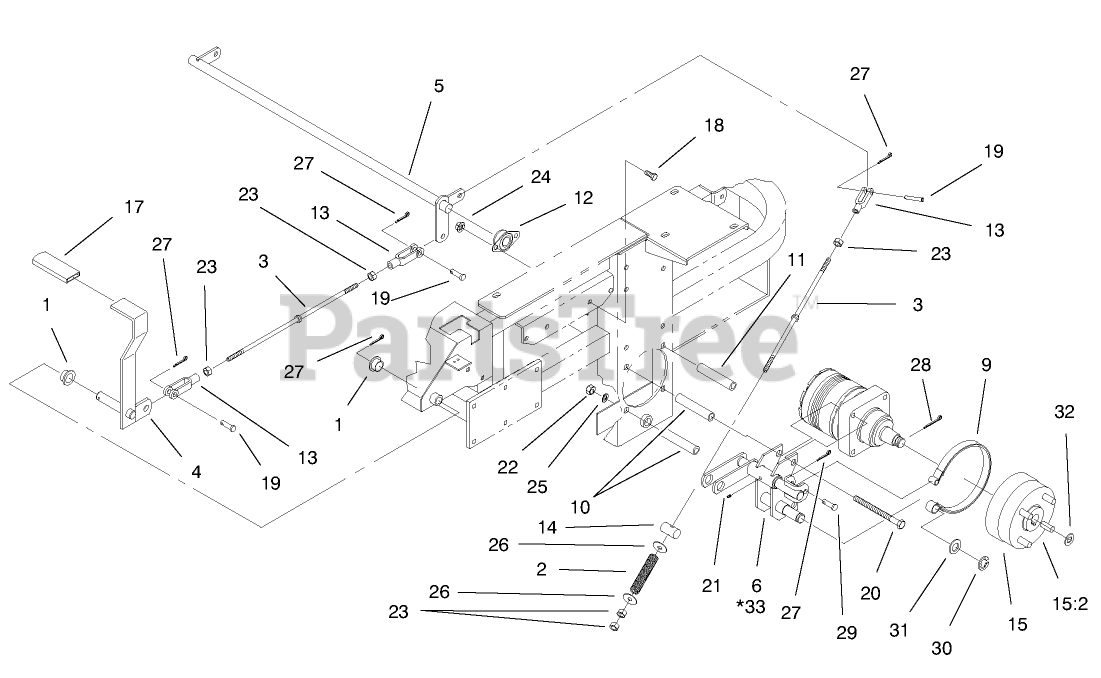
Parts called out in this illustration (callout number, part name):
1	Bearing
2	Spring-Brake
3	Rod-Brake
4	Lever-Brake
5	Shaft-Brake
6	Bracket-Brake LH
9	Band-Brake
10	Spacer
11	Spacer
12	Bearing-Side Flange
13	Yoke-Brake Linkage
14	Pin-Trunion
15	Hub And Drum ASM
15:2	Stud-Wheel
17	Grip-Brake Lever
18	SCREW-HH
19	Pin-Clevis
20	SCREW-HH
21	FITTING-GREASE
22	NUT-HH
23	NUT-HEX
24	NUT-HHF, WHIZ
25	WASHER-LOCK
26	WASHER-FLAT
27	PIN-COTTER
28	Pin-Cotter
29	Pin-Clevis
30	Ring-Retaining
31	WASHER-FLAT
32	Spacer
